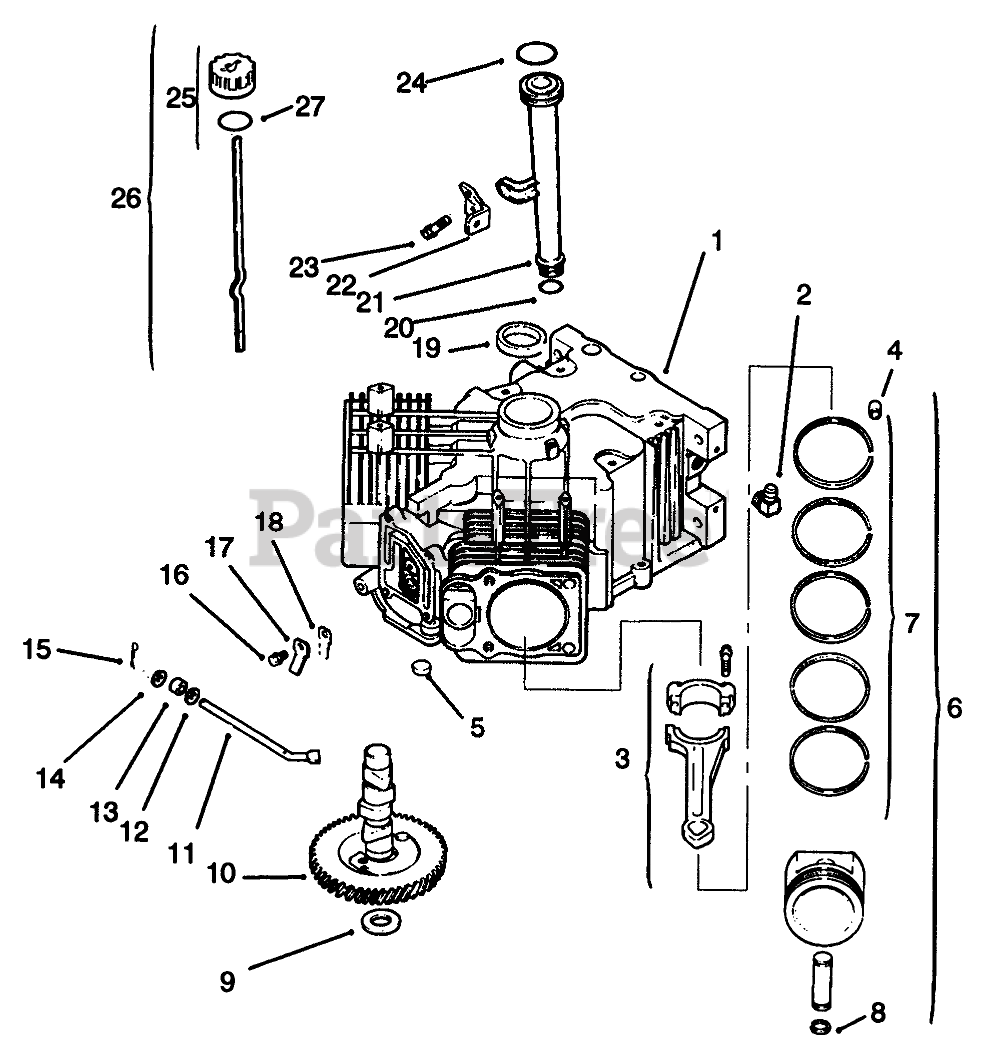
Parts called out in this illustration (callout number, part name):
1	Short Block
2	Connector-90deg.
3	Connecting Rod STD
3	Connecting Rod .25
4	Pin-Dowel
6	Piston ASM STD INC 4/7/8
6	Piston w/Ring Set (.25)
6	Piston w/Ring Set (.50)
7	Set-Ring (Std)
7	Ring Set (.25)
7	Ring Set (.50)
8	Retainer-Piston Pin
9	Shim-Camshaft
10	Camshaft
11	Shaft-Governor Cross
12	Washer
13	Seal
14	Washer
15	Pin-Hitch
16	Screw
17	Retainer-Reed
18	Beed-Breather
19	Seal-Oil
20	"O"Ring
21	Tube-Oil Fill
22	Bracket-Oil Fill Tube
23	Screw-HF
24	"O"Ring-Upper Tube
25	Dipstick INC 26-27
26	Kit-Oil Cap INC 3
27	"O"Ring
